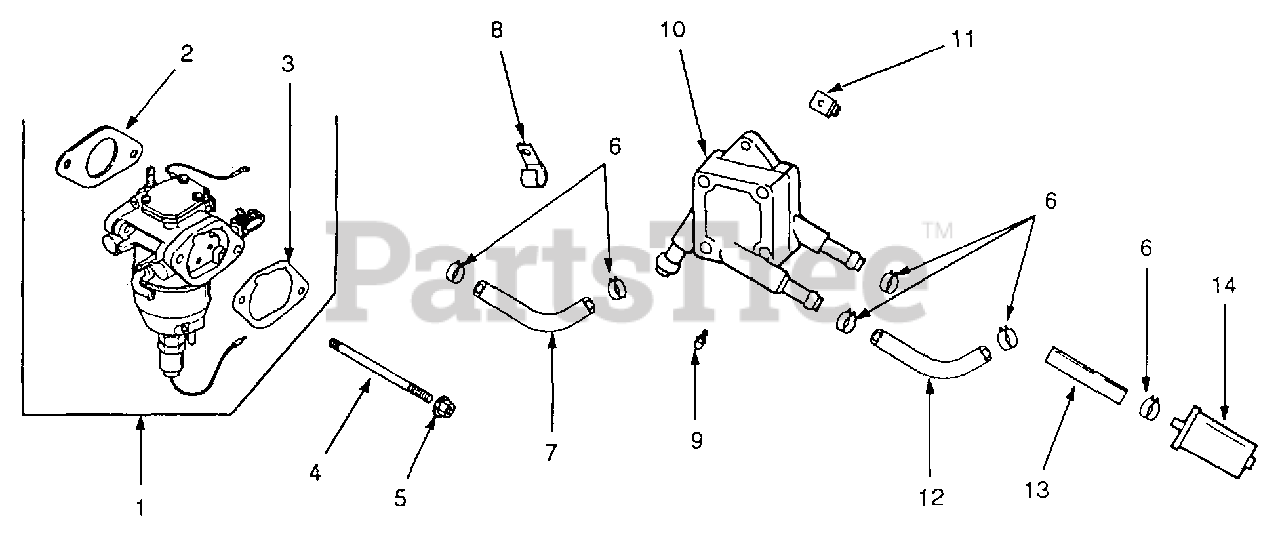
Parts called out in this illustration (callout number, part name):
1	Kit, Carburetor w/Gaskets
2	Gasket, Carburetor
3	Gasket, Air Cleaner Base
4	Stud, M6 x 1.0 x 128
5	Nut, Hex Flange, M6 x 1.0
6	Clamp, Hose
7	Fuel Line 10.5"
8	Clip, Cable
9	Screw, Hex Cap, M6 x 1.7 x 18
10	Pump, Pulse Fuel
11	Nut, Plastic
12	Fuel Line 11.5"
13	Fuel Line 3.5"
14	Filter, Fuel
